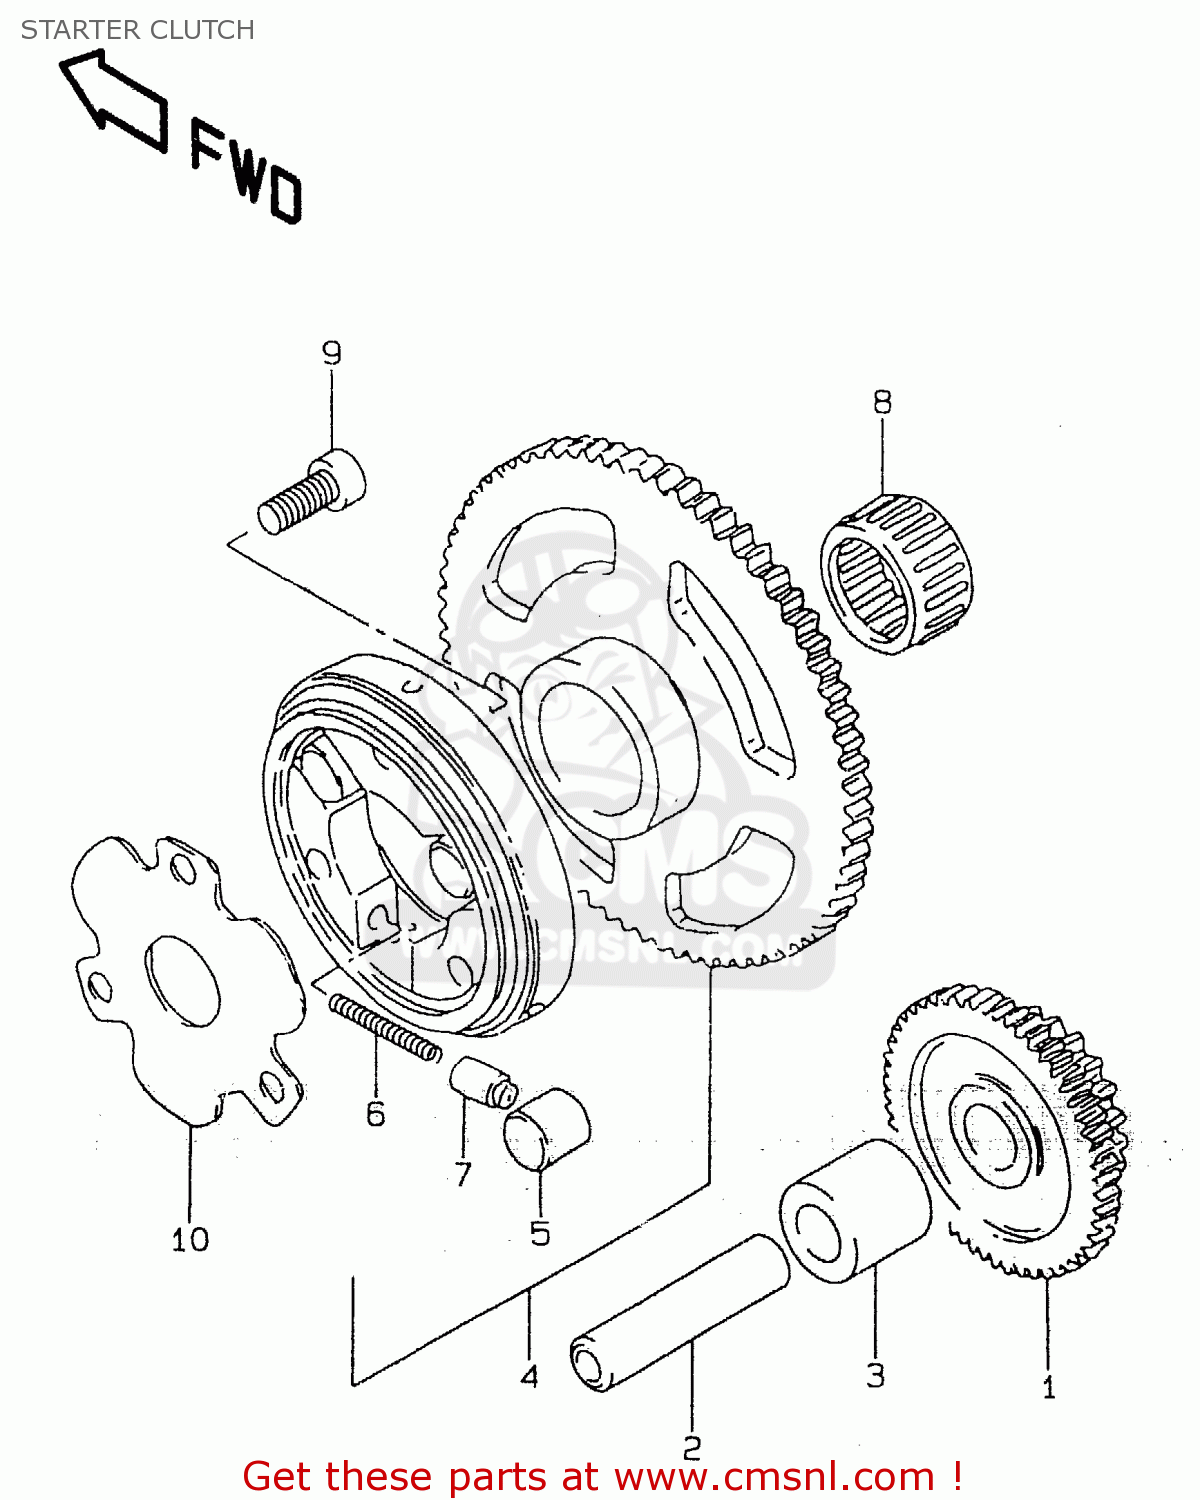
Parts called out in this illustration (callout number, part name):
1	GEAR,STARTER IDLER
2	PIN(7.4X13X56)
3	SPACER(13X19X19)
4	CLUTCH SET,STARTER
5	ROLLER(10X11)
6	SPRING
7	PIECE,STARTER CLUTCH PUSH
8	BEARING(22X28X16)
9	BOLT,OIL FILLE
10	SHIM,STARTER CLUTCH HUB
